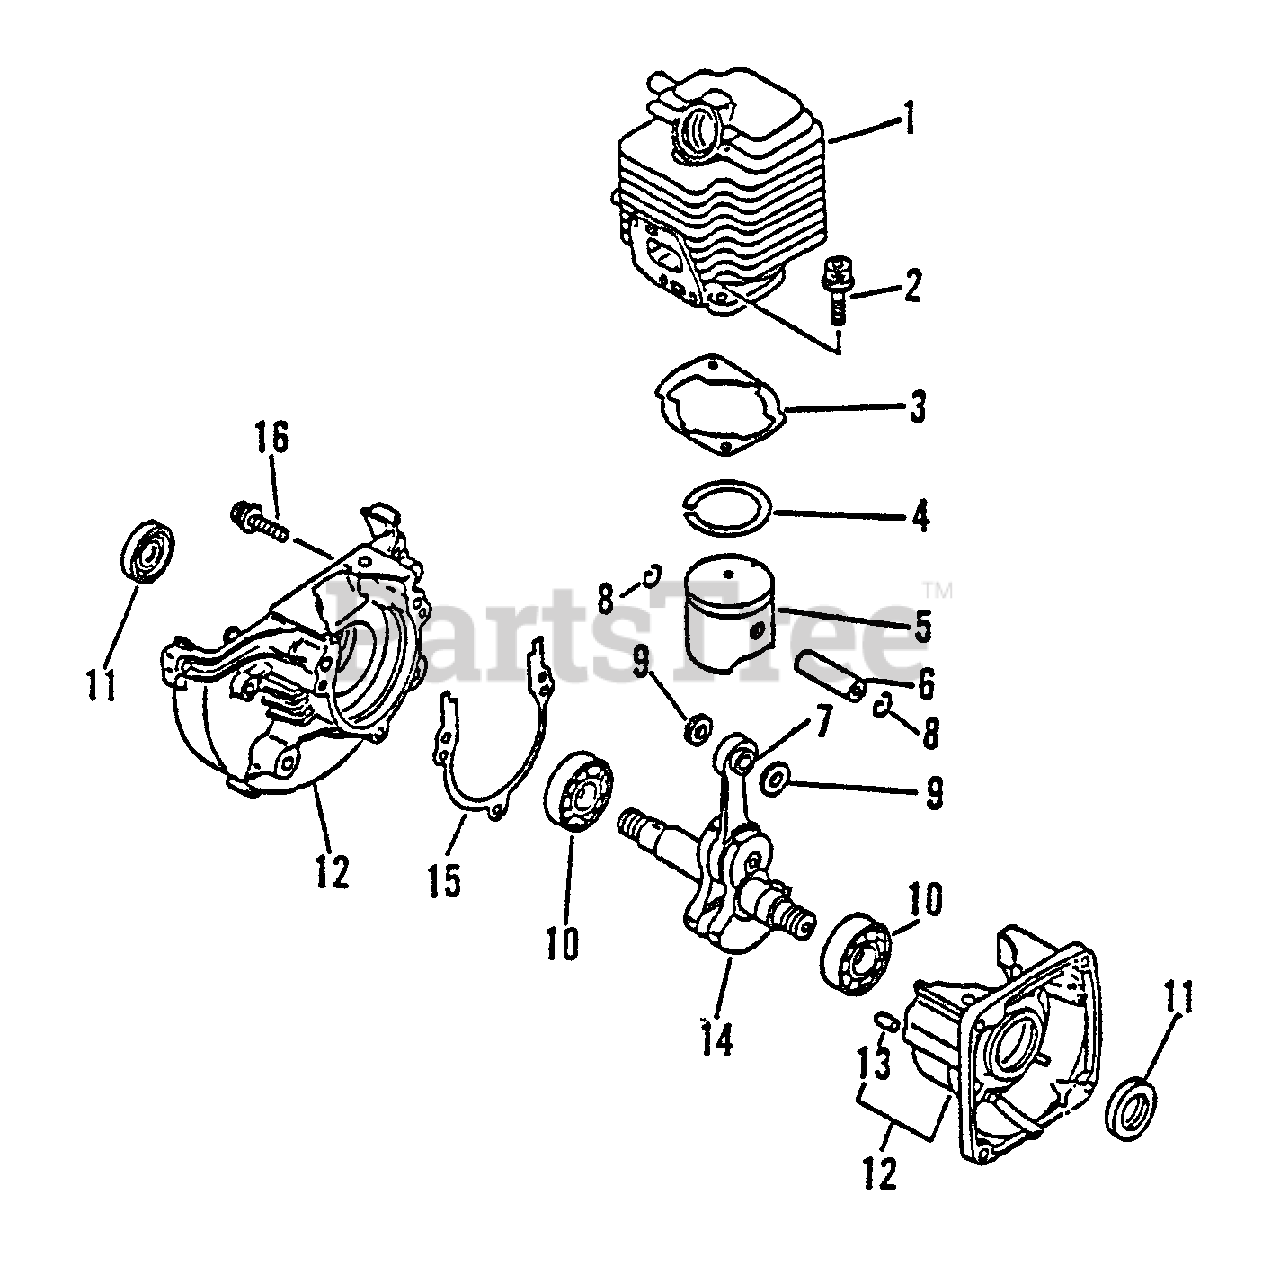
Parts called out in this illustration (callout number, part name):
1	CYLINDER
2	SCREW - 5X22
3	GASKET, CYLINDER
4	PISTON
5	PISTON
6	PIN, PISTON
7	BEARING, NEEDLE
8	RING, RETAINING
9	SPACER, PISTON
10	BEARING, BALL - 6201
11	SEAL, OIL
12	CRANKCASE KIT
13	PIN - LOCATING
14	CRANKSHAFT ASSY
15	GASKET, CRANKCASE
16	SCREW - 5X28
